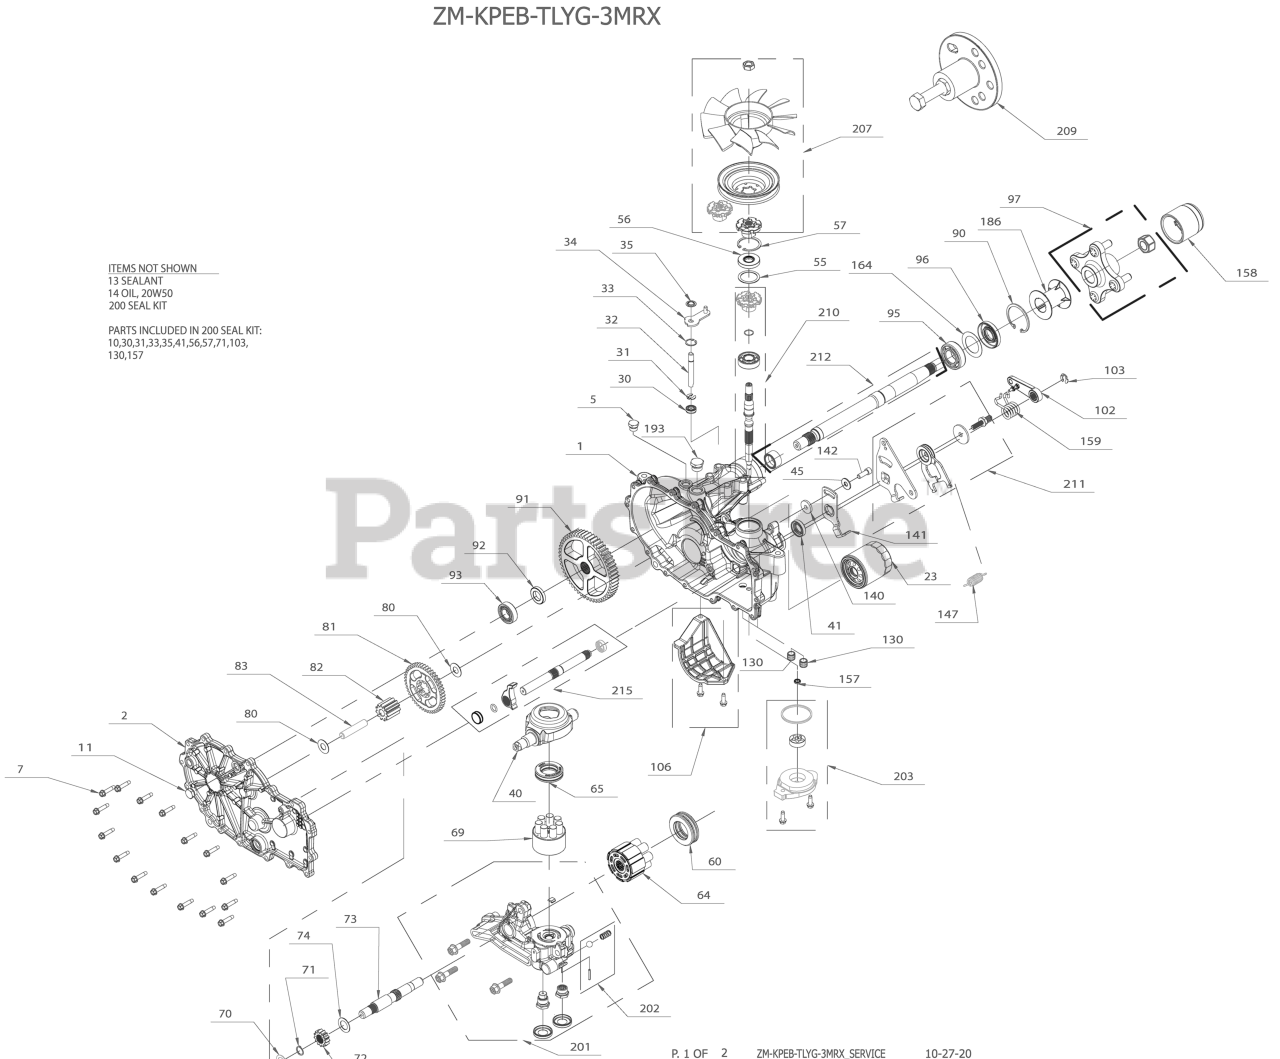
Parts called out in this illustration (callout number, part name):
1	KIT, HOUSING, MAIN, LH, CHRG, CNTL
2	KIT, SIDE COVER, LH
5	PLUG EXT HEX VENT 9/16 18
7	SCREW,HEX WASHER 1/4-20X1.125
11	PLUG EXT HEX VENT 9/16 18
13	SEALANT TUBE 10.1OZ.
14	FLUID, HYDRO 20W50 QT
14	FLUID, HYDRO 15W50 QT
23	FILTER, HYDRO-GEAR 2800 TRANS
30	Seal, lip .375 x 375 x 325
31	RING. RETAINING
32	ROD, BYPASS
33	RING, RET .750
34	HG BYPASS ARM (52370)
35	RING, RTNG .
40	TRUNNION, SWASHPLATE
41	SEAL, LIP 18X32X7
55	WASHER 1.23X1.56X.04
56	SEAL, LIP 17X40X7
57	RING, RET 1.56 INT
60	HG THRUST BEARING (51462)
64	HG 16CC CYLINDER BLOCK (71579)
65	BEARING. THRUST 30 X 52 X 13
69	ASSY, BLOCK 7 PISTON
70	WASHER .63X1.0X.05
71	RING, RET 62 EXT
72	GEAR, 13T, STEEL
73	SHAFT, MOTOR
74	WASHER .71 X 1.16 X .04
80	WASHER .5X1.0X.032
82	GEAR 11 TOOTH STEEL
83	JACK SHAFT (PIN)
90	RING, RETAINING
91	GEAR 54 TOOTH
92	SPACER
93	KIT, BEARING
95	BEARING, BALL 25.4 X 52 X 15
96	SEAL, LIP
97	KIT, HUB 4 BOLT
102	HG ACTUATING KIT HANDLE
103	CLIP,BRAKE ARM HYDROGEAR 52027
106	KIT, FILTER GUARD
130	TUBE CHARGE TRIPLE ORING
141	ARM, NEUTRAL LEFT
142	SHCS 5/16-24X1 PATCH
147	RTN SPRING HG 51605
157	KIT GEROTOR SEAL
158	CAP, AXLE
159	SPRING, TORSION, CW
164	WASHER, 1.355 x 2.035 x .021 FLAT
186	TUBE, AXLE 2.03
201	KIT, CENTER SECTION, LH CHARGE
202	KIT CHARGE RELIEF
203	KIT, CHARGE
207	KIT, FAN / PULLEY
209	HUB PULLER 5 BLT
210	KIT INPUT SHAFT
211	KIT, RTN CCW
212	KIT, SHAFT, AXLE
215	KIT, OUTBOARD, RH ROT B / LH ROT A
